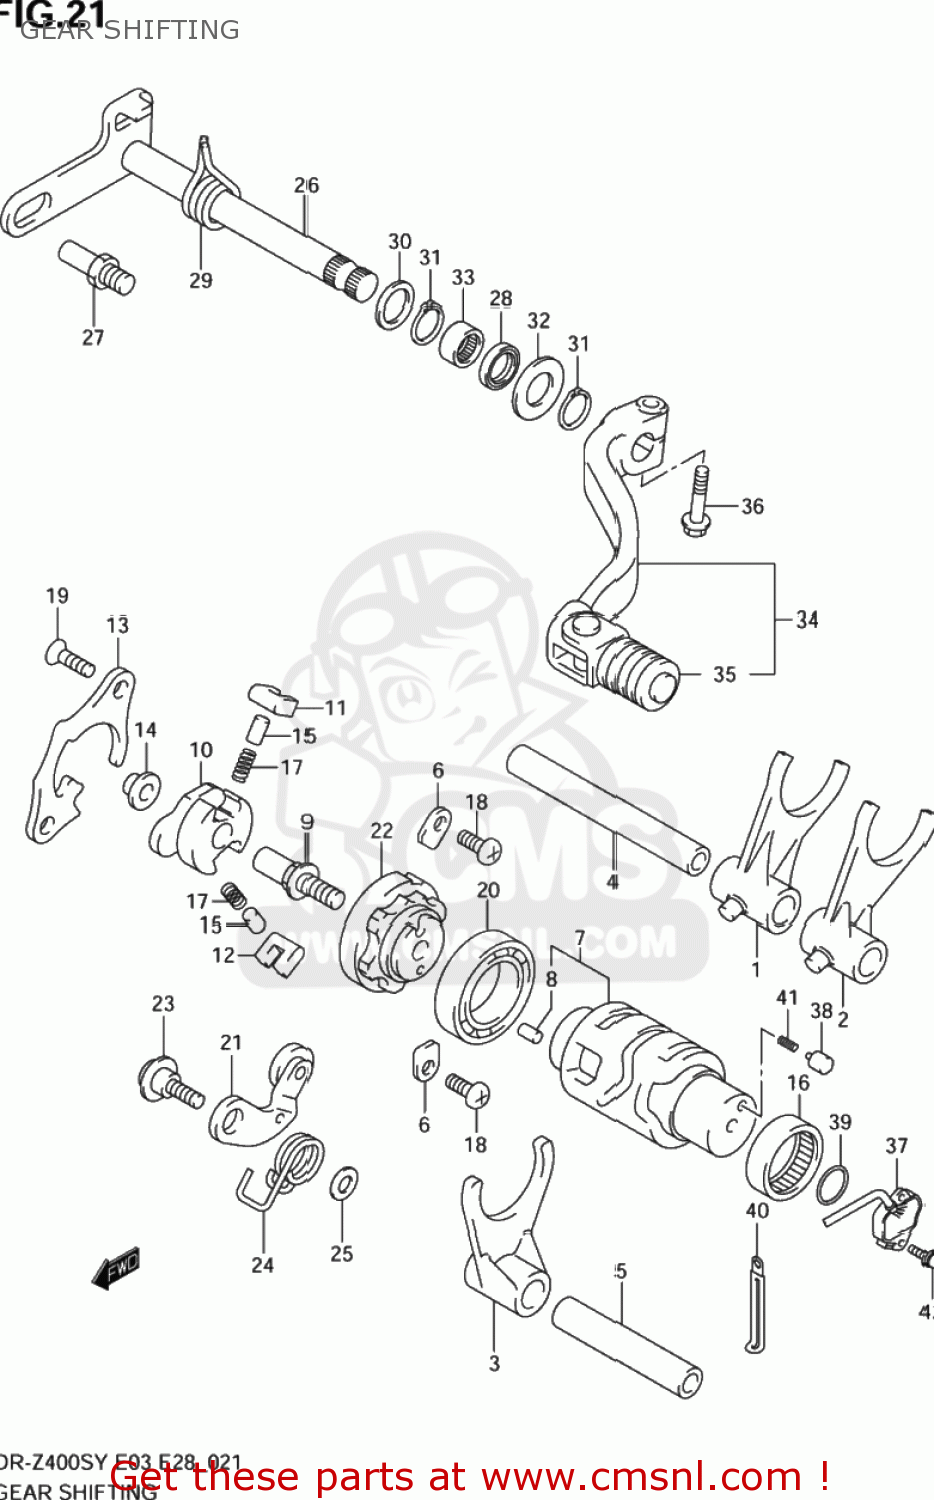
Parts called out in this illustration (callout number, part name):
1	FORK,GEAR SHIFT NO.1
2	FORK,GEAR SHIFT NO.2
3	FORK,GEAR SHIFT NO.3
4	SHAFT,GEAR SHIFT FORK
5	SHAFT,GEAR SHIFT FORK(L:60)
6	RETAINER
7	CAM,GEAR SHIFT
8	PIN
9	PIN,SHIFT CAM DRIVEN GEAR
10	SHIFTER,GEAR SHIFT CAM
11	PAWL,GEAR SHIFT NO.1
12	PAWL,GEAR SHIFT NO.2
13	LIFTER,GEAR SHIFT PAWL
14	SPACER(7X10X5)
15	PIN(5X8)
16	BEARING(25X32X12)
17	SPRING
18	BOLT(6X12)
19	SCREW(6X12)
20	BEARING
21	STOPPER,GEAR SHIFT CAM
22	PLATE,SHIFT CAM STOPPER
23	BOLT,CAM STOPPER ARM
24	SPRING,SHIFT CAM STOPPER
25	WASHER
26	SHAFT,GEAR SHIFT
27	STOPPER,SHIFT ARM
28	SEAL,OIL(14X22X6)
29	SPRING
30	SHIM(14X20X1)
31	CIRCLIP
32	WASHER
33	BEARING(14X20X12)
34	LEVER,GEAR SHF
35	RUBBER,GEAR SHIFT PEDAL
36	SCREW
37	BASE ASSY,GEAR SHIFT TERMINAL
38	PIN(5X15.5)
39	O RING(D:2.4,ID:26.2)
40	CLAMP(L:45)
41	SPRING
42	SCREW
